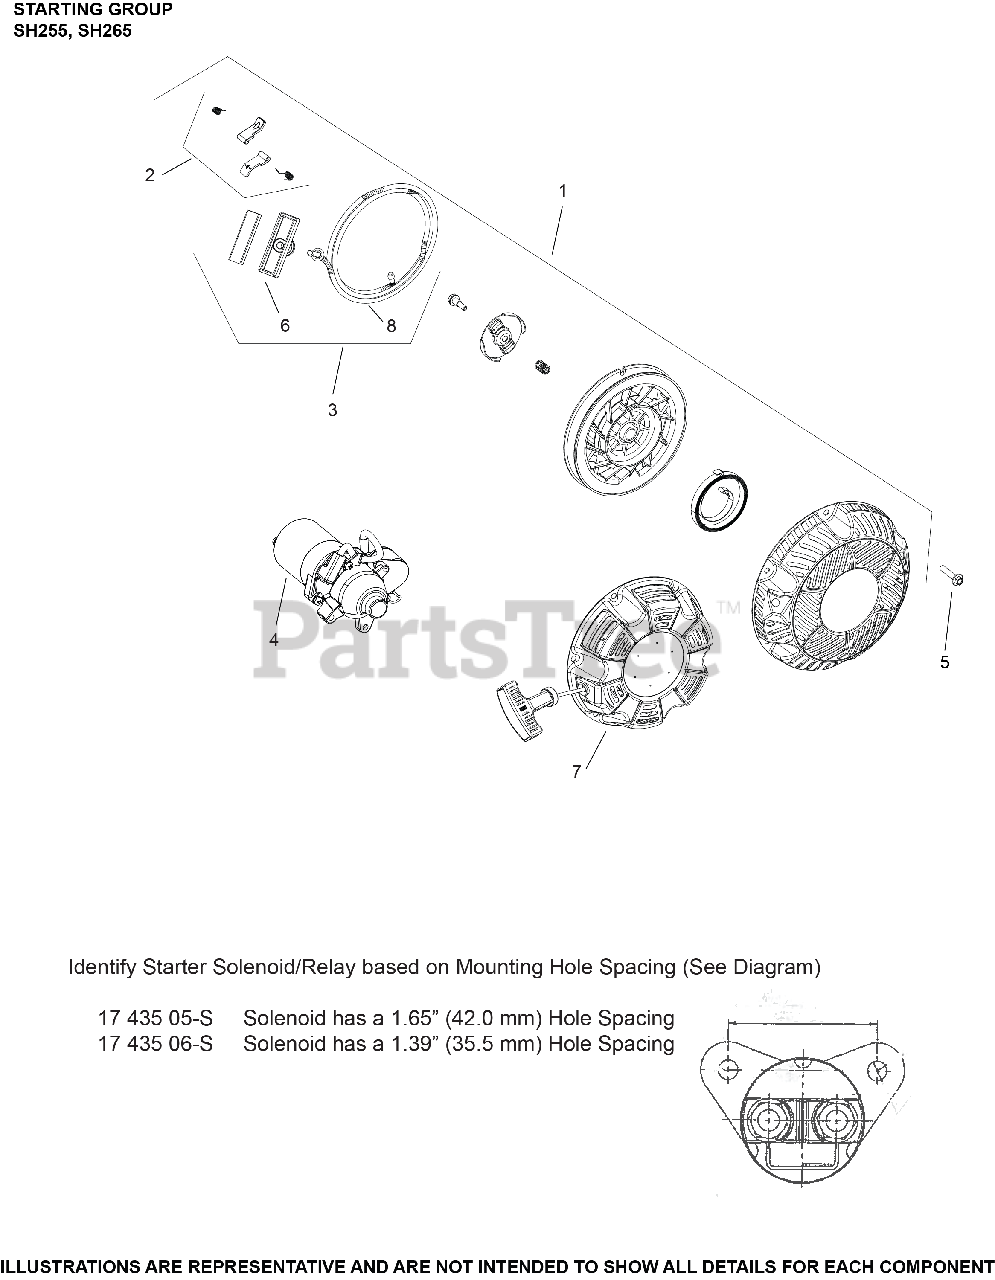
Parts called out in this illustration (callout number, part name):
3	KIT, STARTER ROPE W/HANDLE
7	RETRACTABLE STARTER ASSEMBLY
8	ROPE, STARTING
